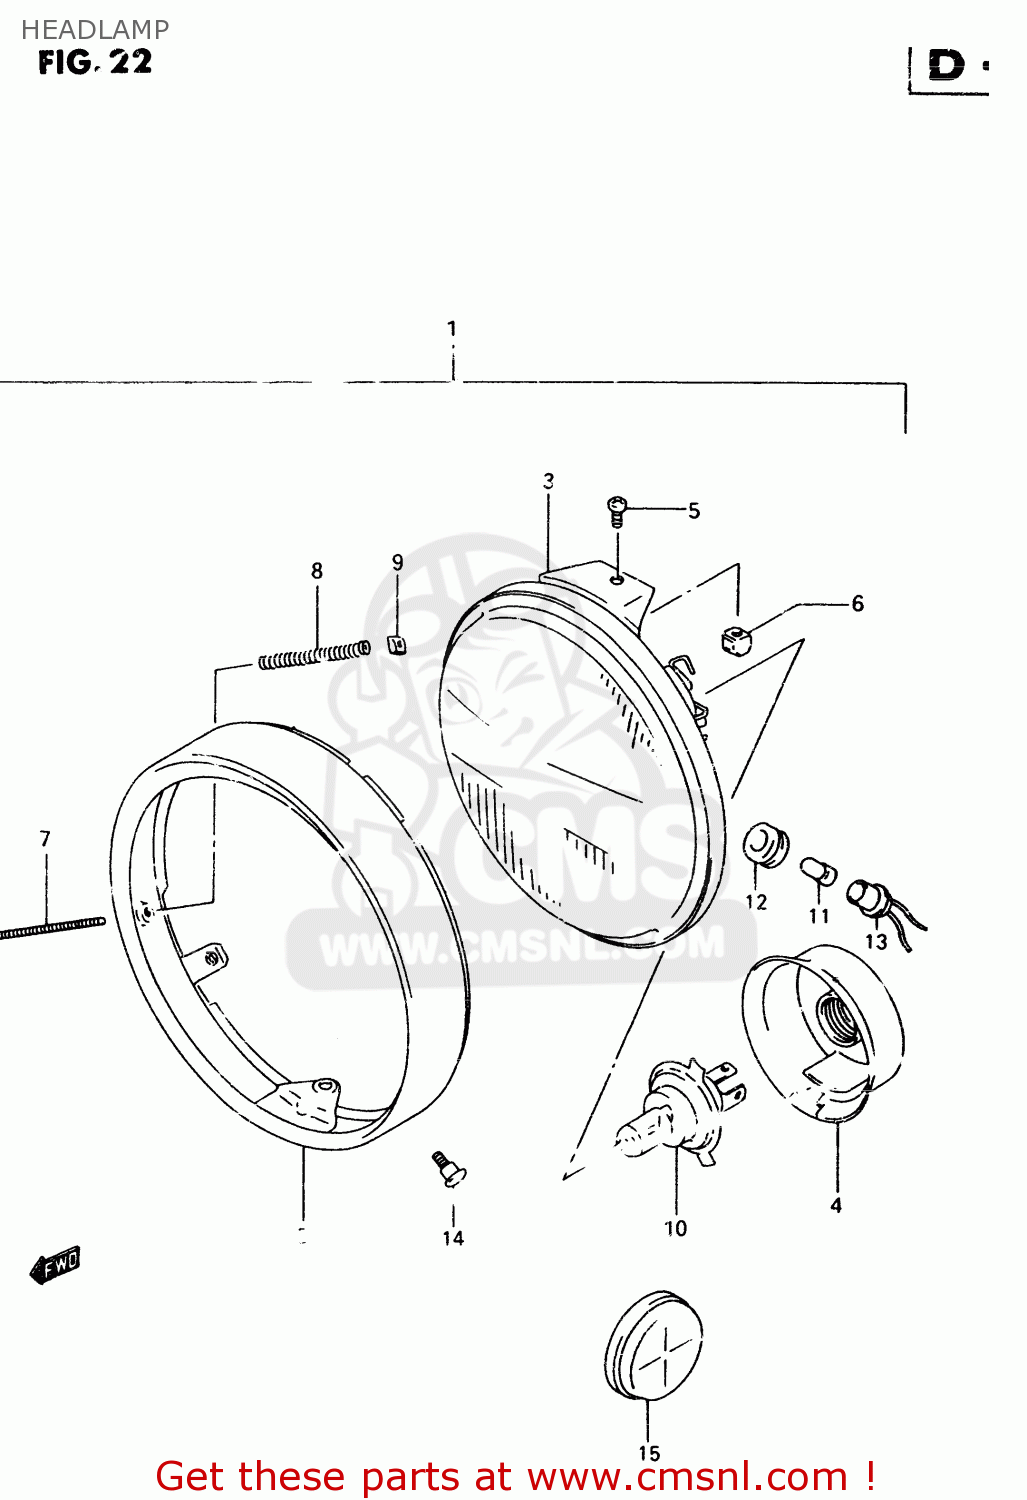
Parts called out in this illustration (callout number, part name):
1	HEADLAMP ASSY
2	RIM
3	UNIT
4	COVER,SOCKET
5	SCREW
6	NUT
7	SCREW(4X50)
8	SPRING
9	NUT
10	BULB(12V60/55W,H4)
11	BULB(12V4W)
12	JOINT,RUBBER
13	CORD,POSITION
14	SCREW(5X12.8)
15	REFLECTOR,REFLEX FR
